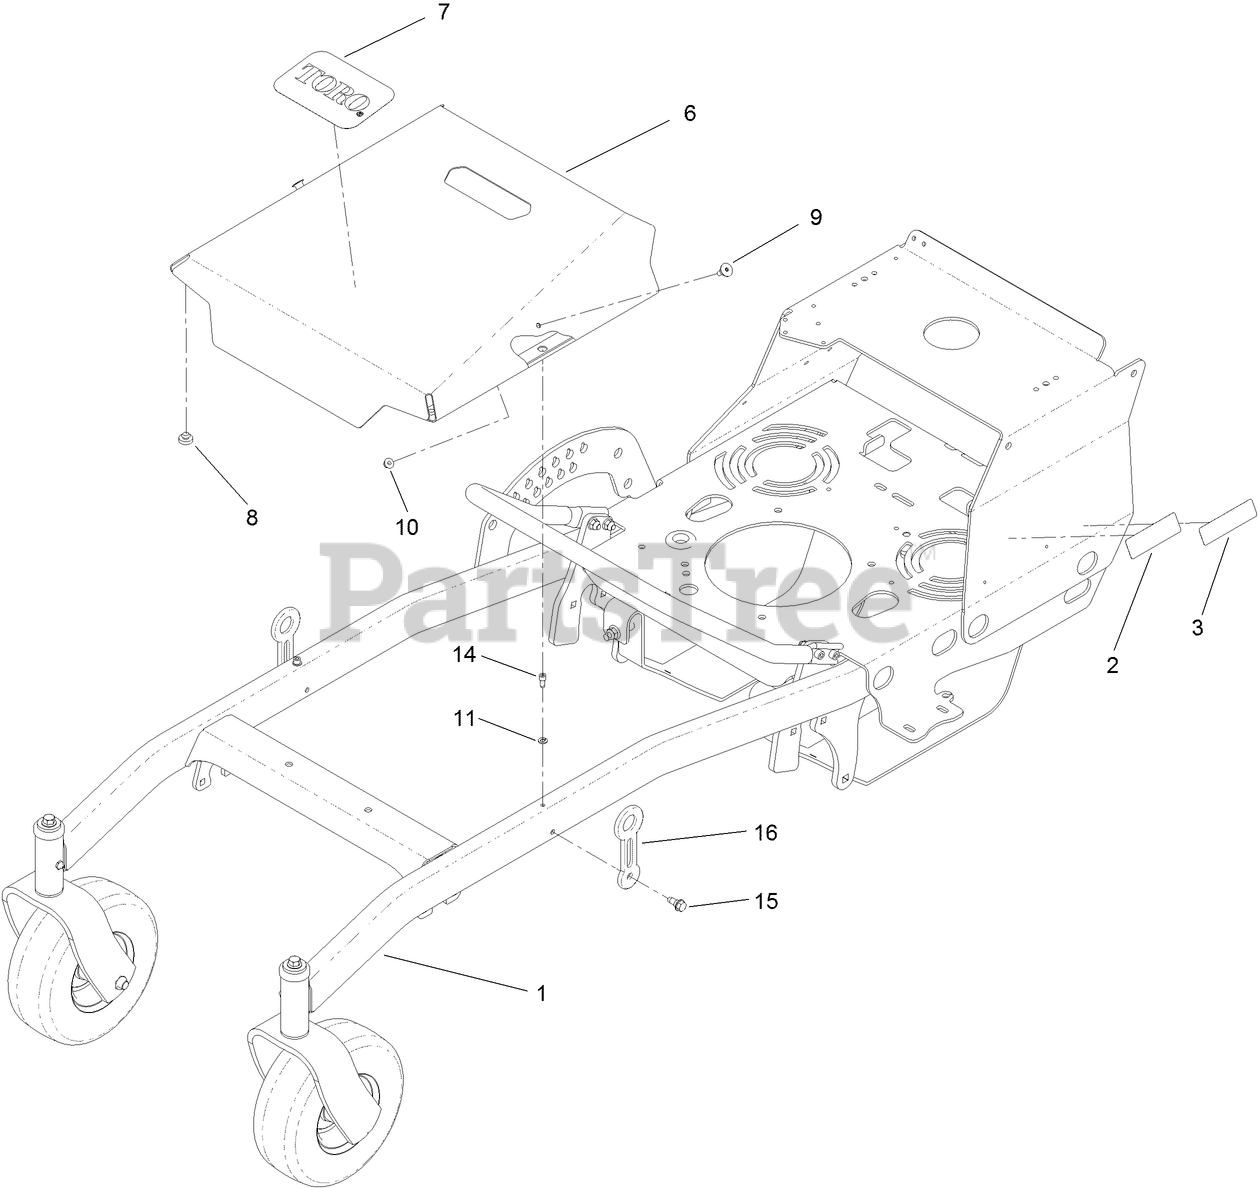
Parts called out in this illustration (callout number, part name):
1	FRAME ASSEMBLY
2	DECAL-EMISSIONS, CARB 2020
3	DECAL-ARRESTOR, SPARK
6	COVER-DECK
7	DECAL
8	BUMPER
10	NUT-HF
11	WASHER-LOCK
14	SCREW-HSH, THREAD FORMING
15	SCREW-SHOULDER
16	LATCH-RUBBER
